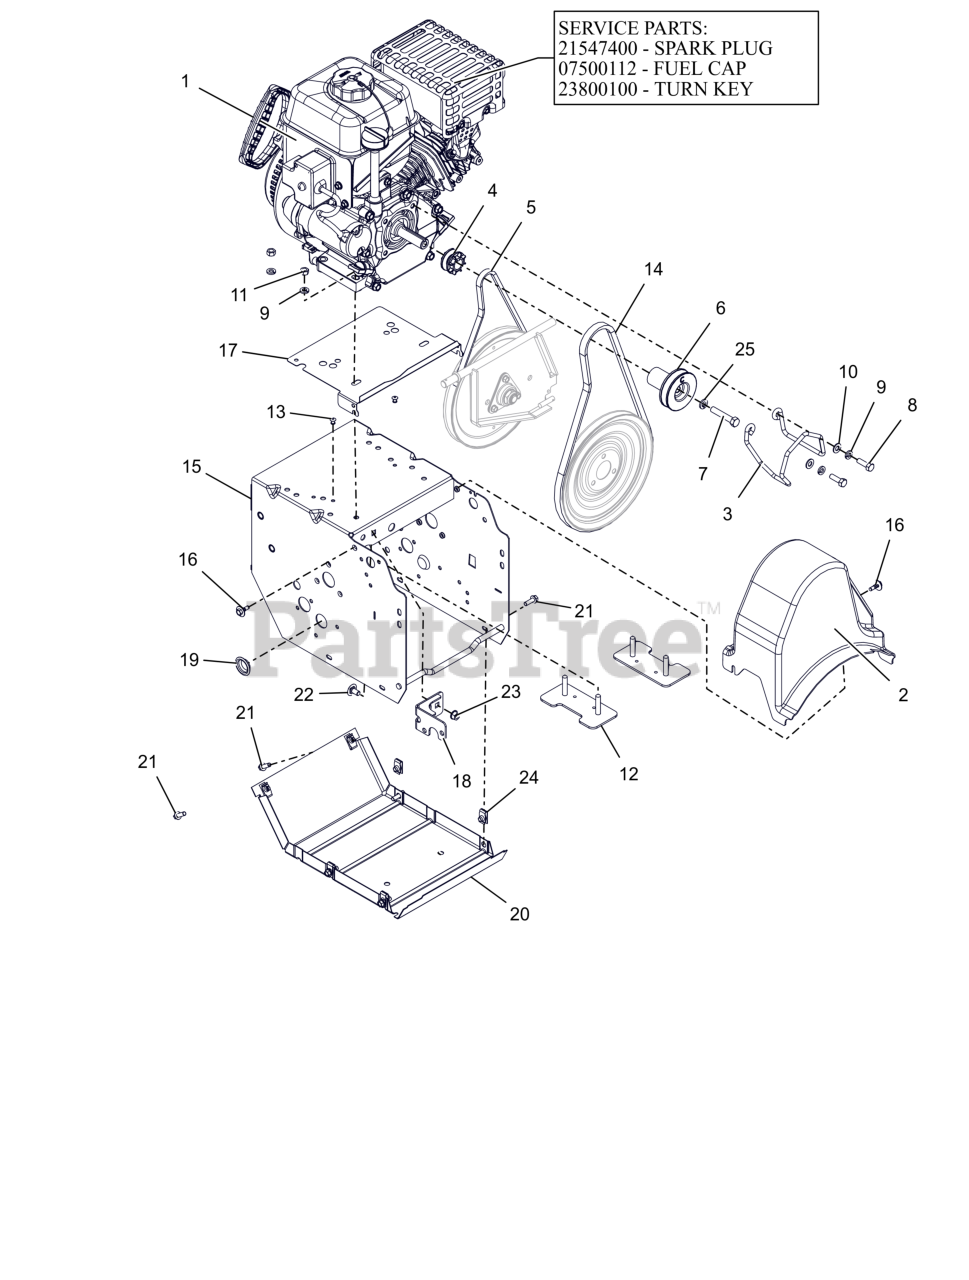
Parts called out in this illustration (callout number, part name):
1	ENGINE, AX223 GEN 2 120V/60W
1	PLUG, SPARK
1	CAP, FUEL TANK (BLACK)
1	KEY, TURN LCT (RED/2 PACK)
2	COVER, COMPACT BELT
3	FINGER, BELT
4	SHEAVE, TRACTION
5	V-BELT, 3L-WRAPPED
6	SHEAVE, ATTACHMENT SINGLE GRV
7	BLT, HEX .38-24X2.00 G5 ZCC
8	BLT, HEX 0.3125-24X1 G5 ZCC
9	WSHR, LK-HVY .312X.097 ZCC
10	WSHR,FLT .344X.688X.065 ZCC
11	NUT, HEX .312-18 ZCC
12	STRAP, ENGINE BOLT-WELDMENT
13	RVT, POP .1875 ZCC
14	V-BELT, HA-RAW EDGE
15	FRAME, MAIN
16	SCR-TAP .25-20X.5 CAPTIVE
17	BAFFLE, COMPACT
18	WELDMENT, FRAME BRACKET
19	PLUG, HOLE - 1.00" FLEXTEMP
20	COVER, BOTTOM
21	BLT, HWH .25-20X.75 G5 ZCC
22	BLT, RHSSN .31-18X.625 G5 ZCC
23	NUT-LK-TOP-FLG .312-18 GF ZCC
24	NUT-RTNR .25-20X.56
25	WSHR,LK-REG .375X.094 ZCC
